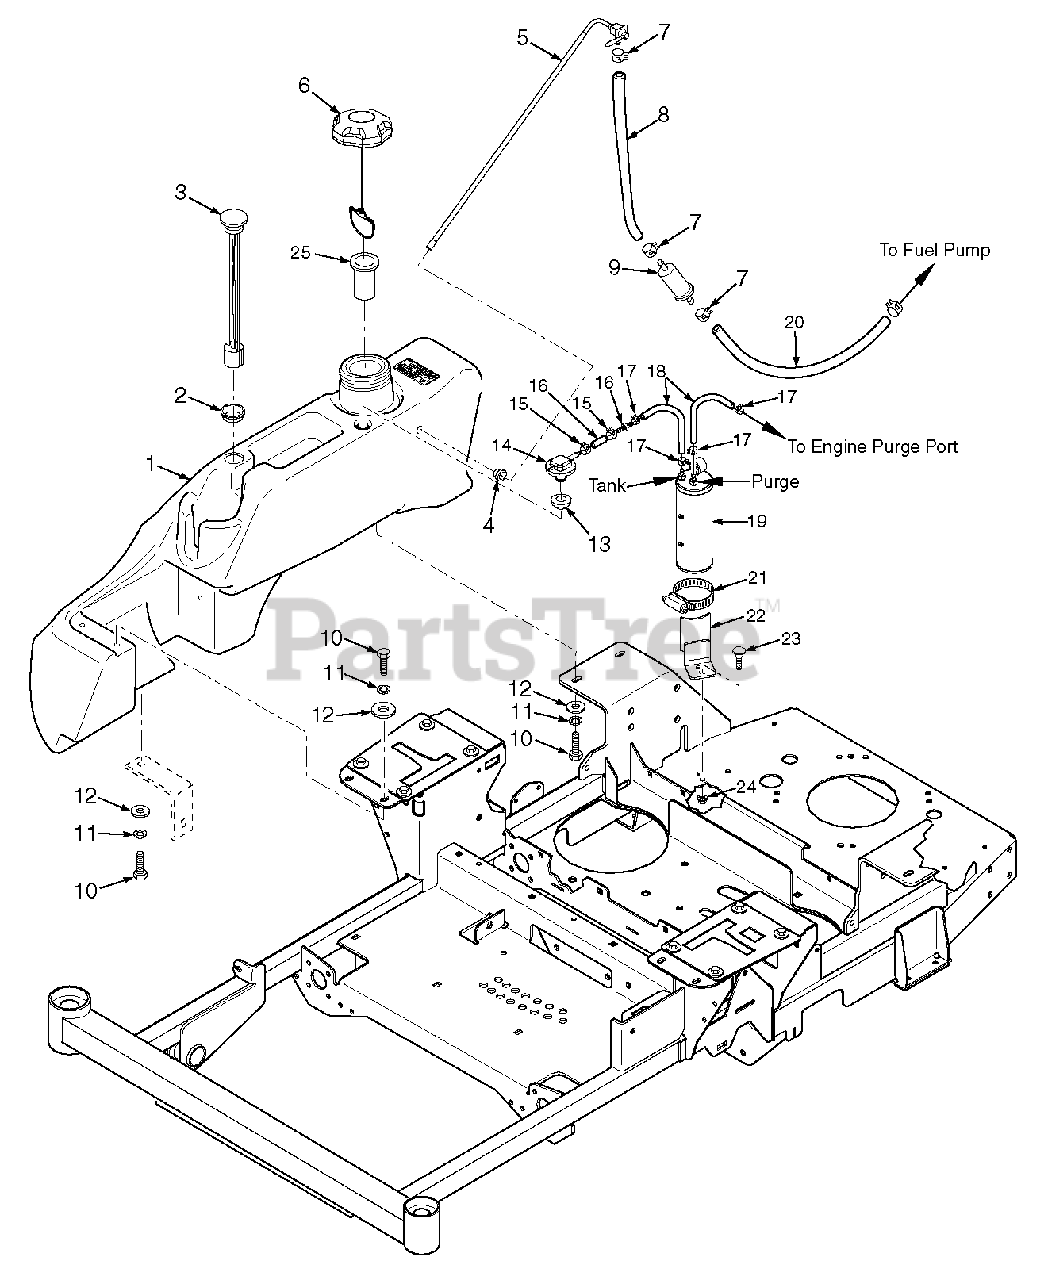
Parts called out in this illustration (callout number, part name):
1	Fuel Tank Assembly
2	Grommet
3	Fuel Gauge Assembly
4	Bushing, .56 Dia. Viton
5	Fuel Tube Assembly
6	Fuel Cap, Tethered
7	Clamp, Fuel Hose 1/4"
8	Fuel Hose, 1/4" Non-Perm
9	Fuel Filter
10	Bolt, Hex Head 5/16-18 x 3/4"
11	Lockwasher, 5/16" Spring
12	Flatwasher, 5/16-.375 x .875 x .083
13	Grommet, Viton
14	Remote Vent
15	Clamp, Fuel Hose 7/32"
16	Hose, 1/4" Vapor Recovery
17	Clamp, Vapor Recovery Hose
18	Hose, 3/16"
19	Carbon Canister
20	Fuel Hose
21	Clamp, Hose
22	Bracket Weldment, SFZ48/52
22	Bracket Weldment, SFZ61
23	Bolt, Carriage 5/16-18 x 3/4"
24	Nut, Serrated Flange 5/16-18
25	Tube, Fuel Tank Insert
26	Mender, 1/4 x 3/16 w/0.02 Hole
